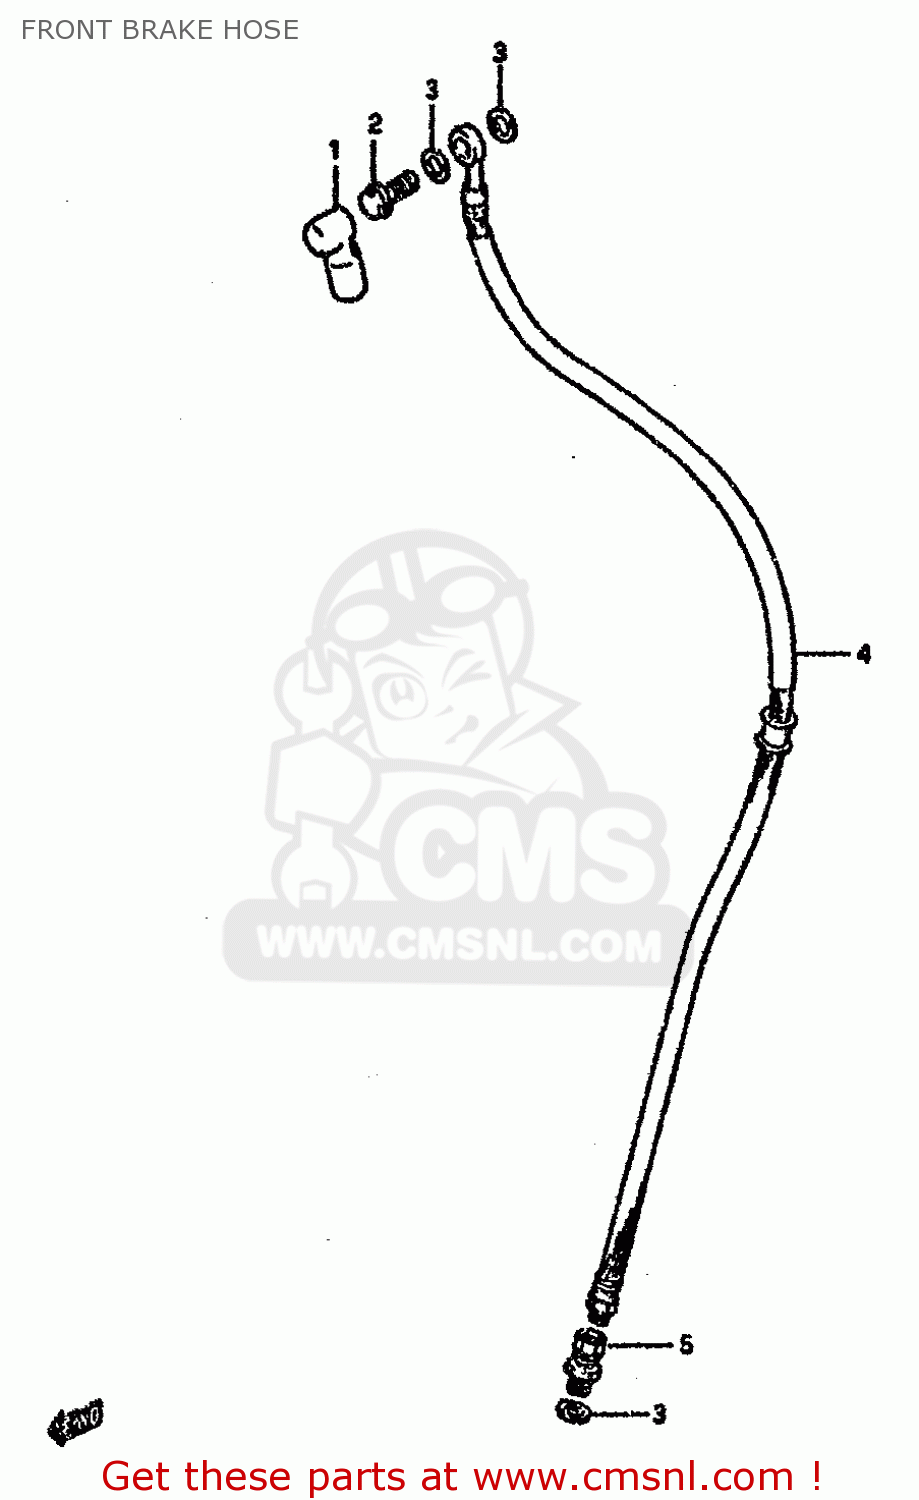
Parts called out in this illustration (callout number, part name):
1	BOOT,MASTER CYLINDER
2	BOLT UNION
3	WASHER(10X15X1.5)
4	HOSE,FR BRAKE
5	ADAPTOR,BRAKE HOSE
